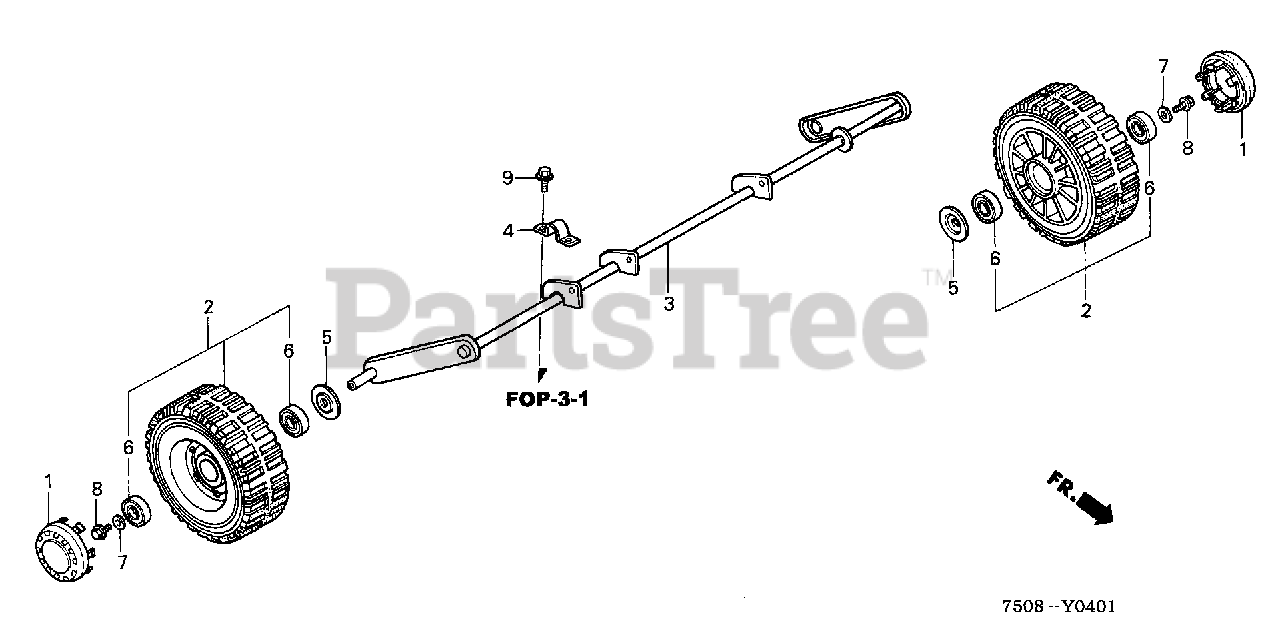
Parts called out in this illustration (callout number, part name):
1	CAP, WHEEL
2	WHEEL (6-2.0)
3	SHAFT
4	BRACKET, R. SHAFT
5	WASHER, SPECIAL (12MM)
6	BEARING, RADIAL BALL
7	WASHER, PLAIN (6MM)
8	BOLT, FLANGE (6X12)
9	BOLT, FLANGE (8X20)
